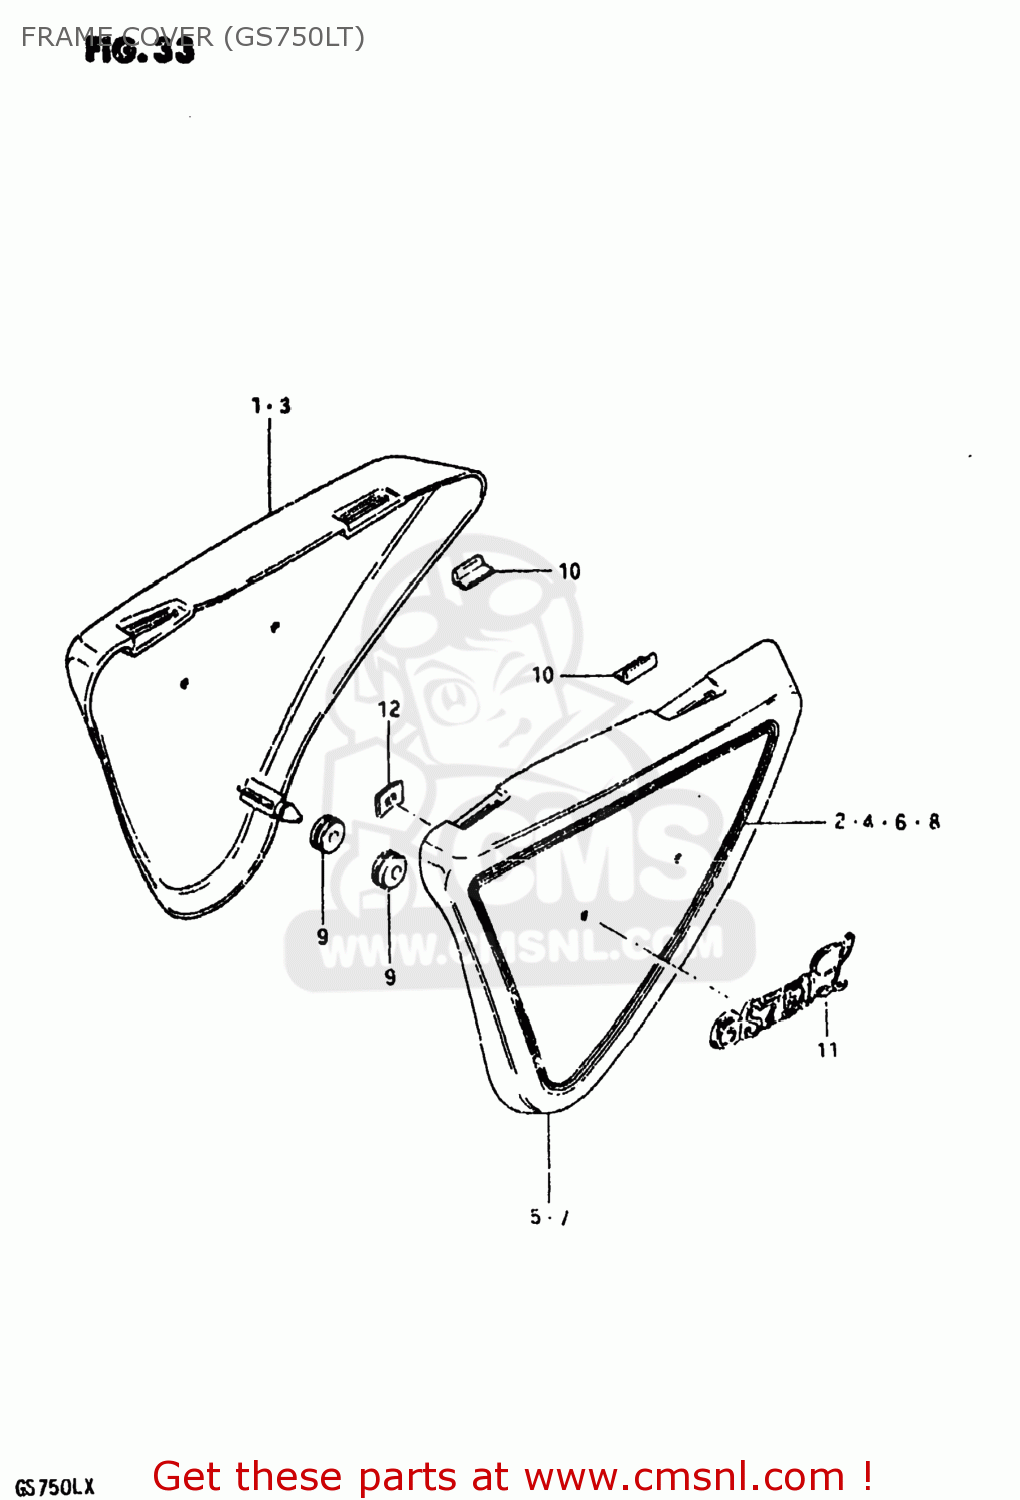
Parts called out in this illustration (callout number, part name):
1	COVER,FRAME,RIGHT
2	TAPE SET,FRAME COVER,RIGHT
3	COVER,FRAME,RIGHT
4	TAPE SET,FRAME COVER
5	COVER ASSEMBLY,FRAME,LEFT
6	TAPE SET,FRAME COVER,LEFT
7	COVER ASSEMBLY,FRAME,LEFT
8	TAPE SET,FRAME COVER
9	CUSHION
10	CUSHION,FRAME COVER
11	EMBLEM,FRAME COVER
12	NUT
